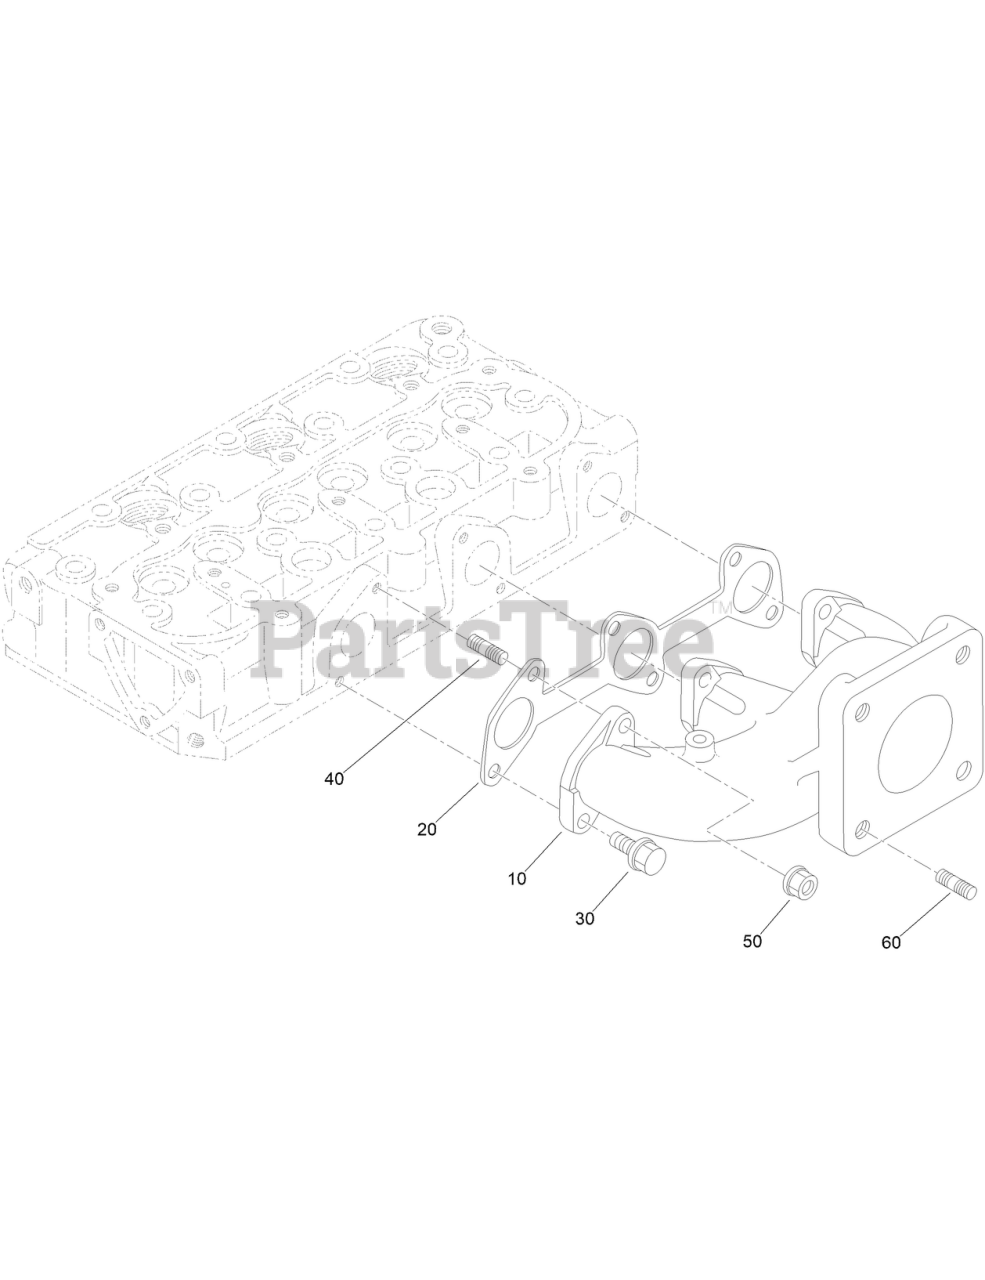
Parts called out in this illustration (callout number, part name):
10	MANIFOLD,EXHAUST
20	GASKET-MANIFOLD, EXHAUST
30	BOLT,UBS
40	BOLT-STUD
